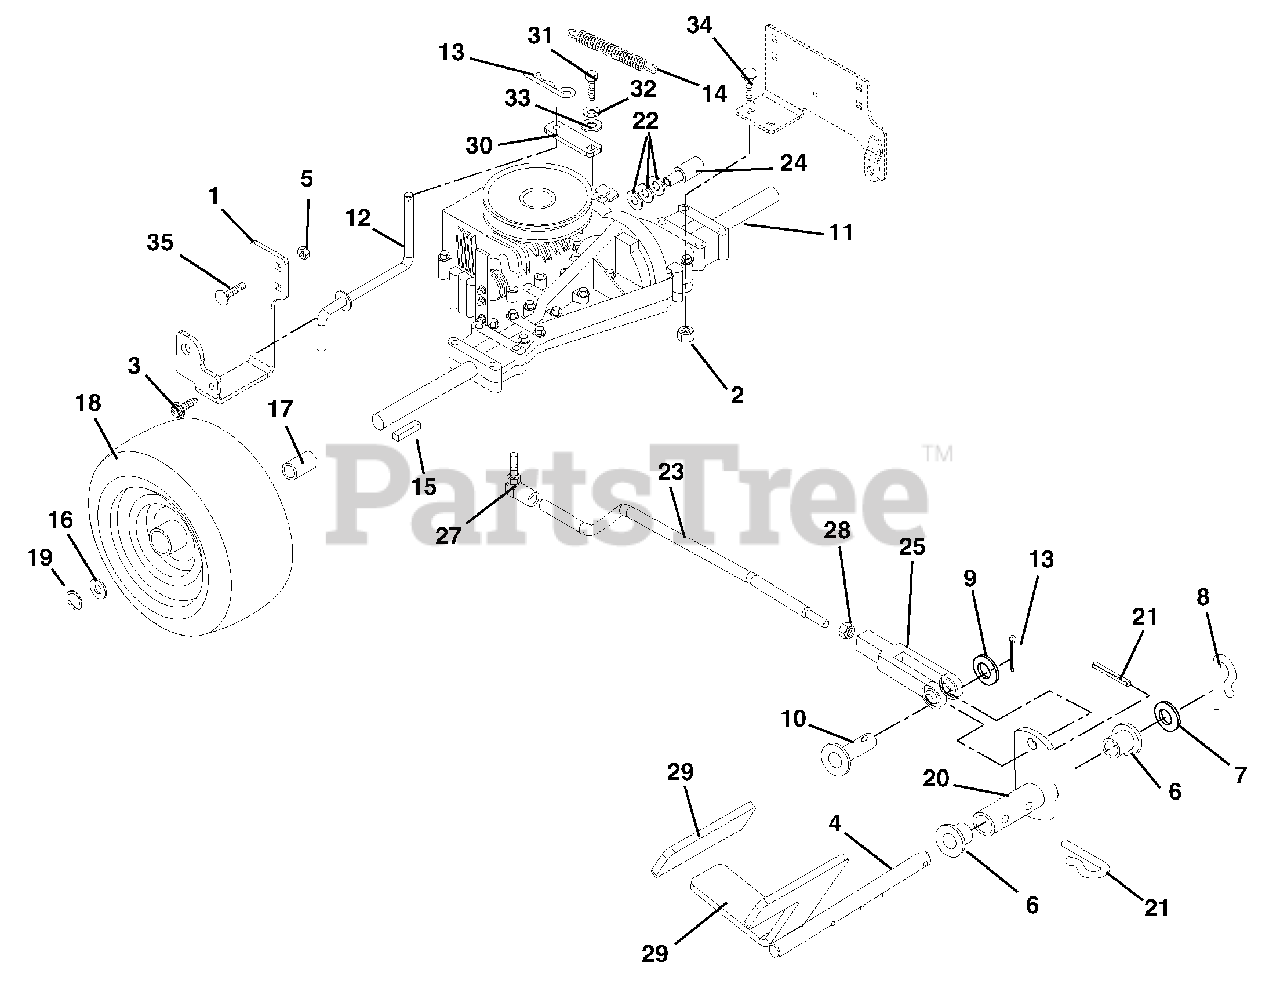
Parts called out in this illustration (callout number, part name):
1	Support, Transmission
2	Nut, Flange .50-13
3	Screw-Tapping .31-18 x .75 Hex Washer Head
4	Weldment, Forward and Reverse Pedal
5	Nut, Locking Top Flange .38-16
6	Bushing, Flange .515 x .75 x .745 x 1.00
7	Washer, Flat Steel .505 x 1.00 x .062
8	Clip, Spring
9	Washer, Flat Steel .38 x .87 x .179
10	Pin, Clevis .31 x .822
11	Transmission Peerless Hydro
12	Rod, Transmission Disconnect
13	Pin, Hair
14	Spring, Tension .043 x .44 x 3.31
15	Key, Square .188 x 2.0 x .188
16	Washer, Flat Steel .755 x 1.25 x .125
17	Spacer, Wheel .75 x 1.00 x 1.25
18	Assembly, Tire and Wheel 16 x 6.5 x 8 (060, 062)
18	Assembly, Tire and Wheel 480 x 8 (064)
18	Tire 16 x 6.50-8 2 Pulley
19	Ring, Retaining External .75 x .05
20	Weldment, Shift Rod and Hub
21	Pin, Spring Clip
22	Washer, Flat, Steel .50 x 1.00 x .062
23	Rod, Rear Engine Rider Shift
24	Trunnion
25	Yoke .31-24 x 2.250
26	Washer, Flat Steel .390 x .750 x .125
27	Ball Joint
28	Nut-Locking-Nylon .375-24 With Insert
29	Grip, Pedal
30	Tab, Transmission Disconnect
31	Bolt-Hex .25-28 x .75 Grade 5
32	Washer, Locking .25 x .062 Regular
33	Washer, Flat Steel .328 x 1.00 x .094
34	Bolt, Round Head Square Neck .31-18 x 2.50 Grade 5
35	Bolt, Round Head Square Neck .38-16 x .75 Grade 5
